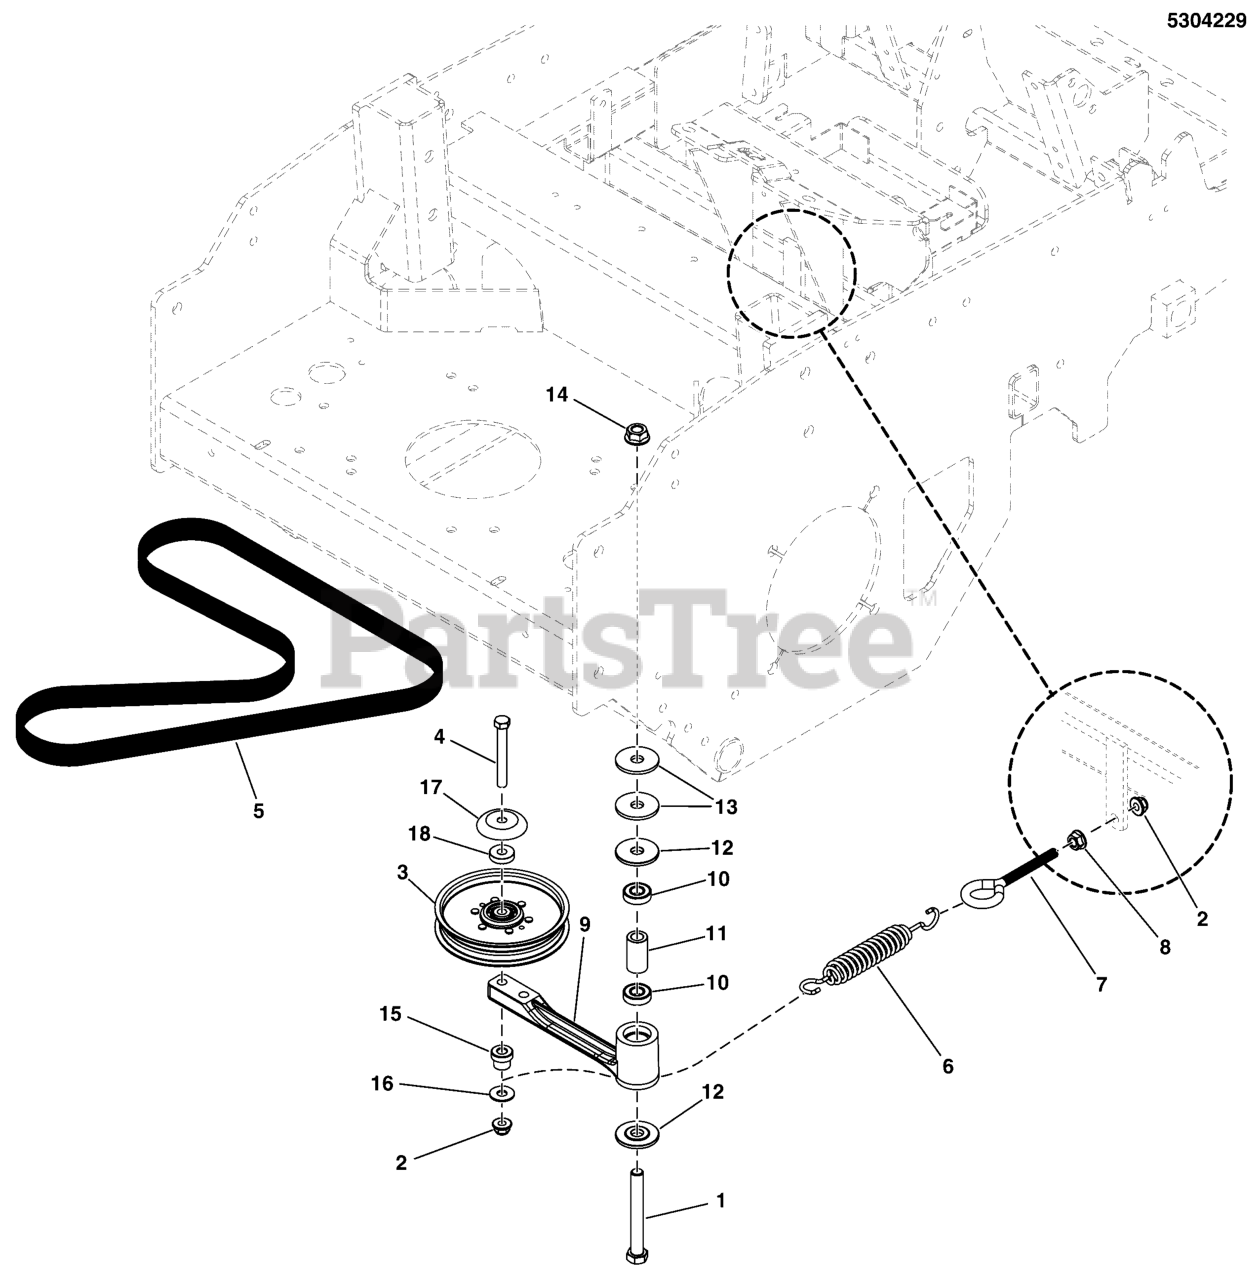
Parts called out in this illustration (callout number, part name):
1	BOLT, 1/2-13 X 4" GD5 CZ
2	NUT, 3/8-16 HEX NYLOCK FLANGE
3	PULLEY-IDLER, 5.00OD, .385ID, .75W, STL
4	BOLT, 3/8-16 X 3-1/2" GD5 CZ
5	BELT, HB, 65.1"EL
6	SPRING-EXT, 1.04 ODX6.935LGX.148WR, BLK
7	EYE BOLT, 3/8-16 X 5, 2.88THRD, 1EYE, CZ
8	NUT, 3/8-16 HEX SERRATED FLANGE
9	ASSM, IDLER ARM, PUMP DRIVE, 1/2ID, CAST (5101178A)
10	BEARING, BALL, AXLE
11	SPACER, .52 X .84 X 1.53, PM
12	SPACER, IDLER ARM, 1/2, PM
13	WASHER, .52 X 1.75 X .14, CZ
14	NUT, Hex Flange, Nylock, 1/2-13
15	BUSHING, .38 X .88 X .73
16	WASHER, 3/8 USS
17	SHIELD, BEARING PULLEY, 3/8ID, CZ
18	SPACER, .39 X 1.00 X .25, PM, CZ
